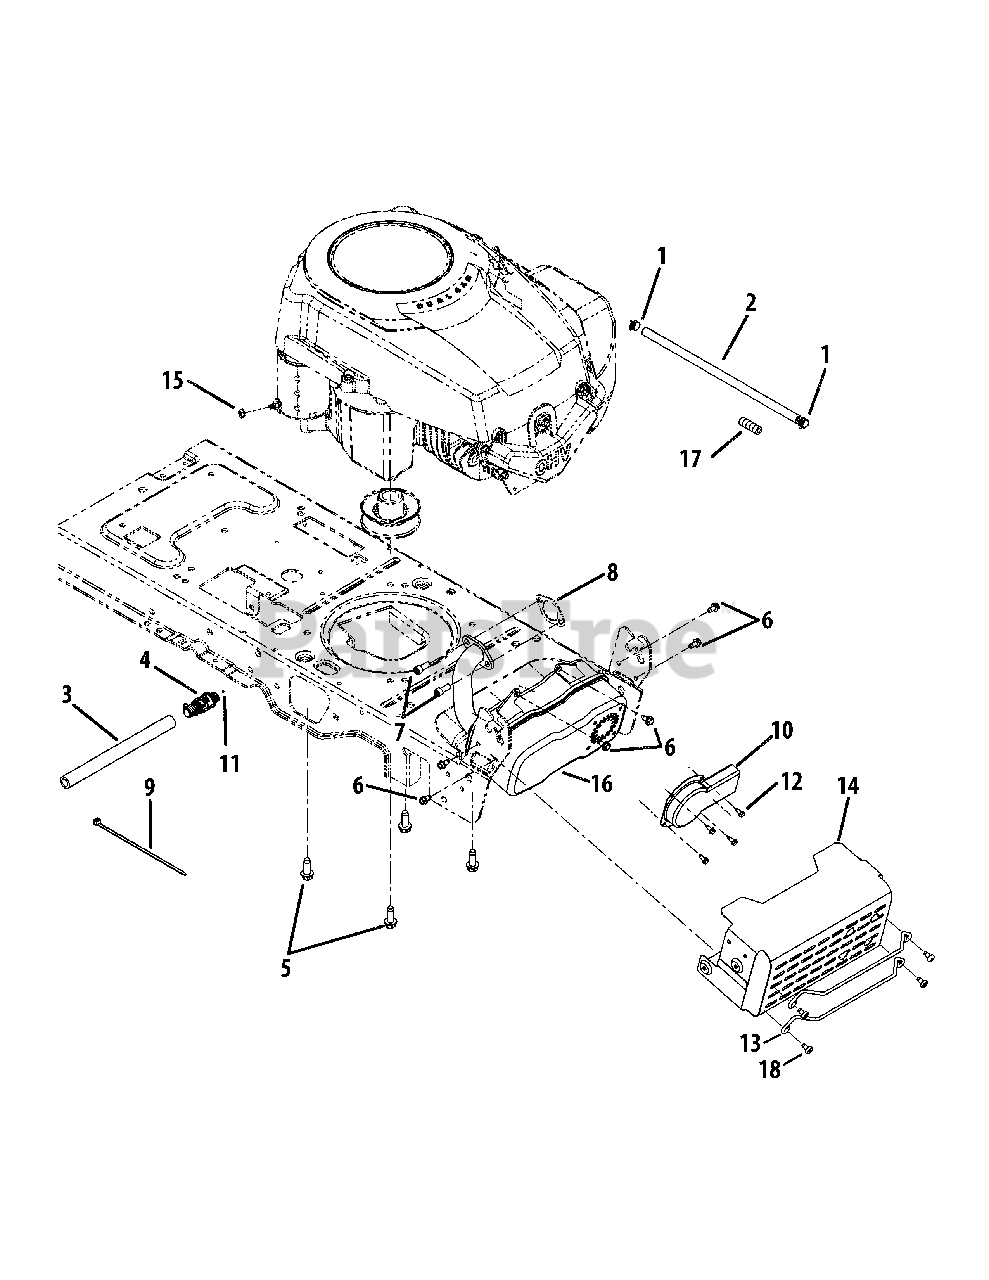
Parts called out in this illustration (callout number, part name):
1	Hose Clamp
2	Fuel Line 16" Lg.
3	Oil Drain Hose
4	Oil Drain
5	TT Screw 3/8-16 x 1.00
6	Hex Wash S-Tapp Scr 1/4-20 x .50
7	Screw 5/16-18 x .75
8	Exhaust Gasket
9	Cable Tie
10	Long Muffler Deflector
11	Pipe Sealant
12	Hex AB Scr #8-18 x .50
13	Muffler Guard Rod
14	Muffler Shield Assembly
15	Hex Sems Nut 1/4-20
16	Muffler
17	Vent Hose
18	TT Pan Hd Scr. 1/4-20 x .50
